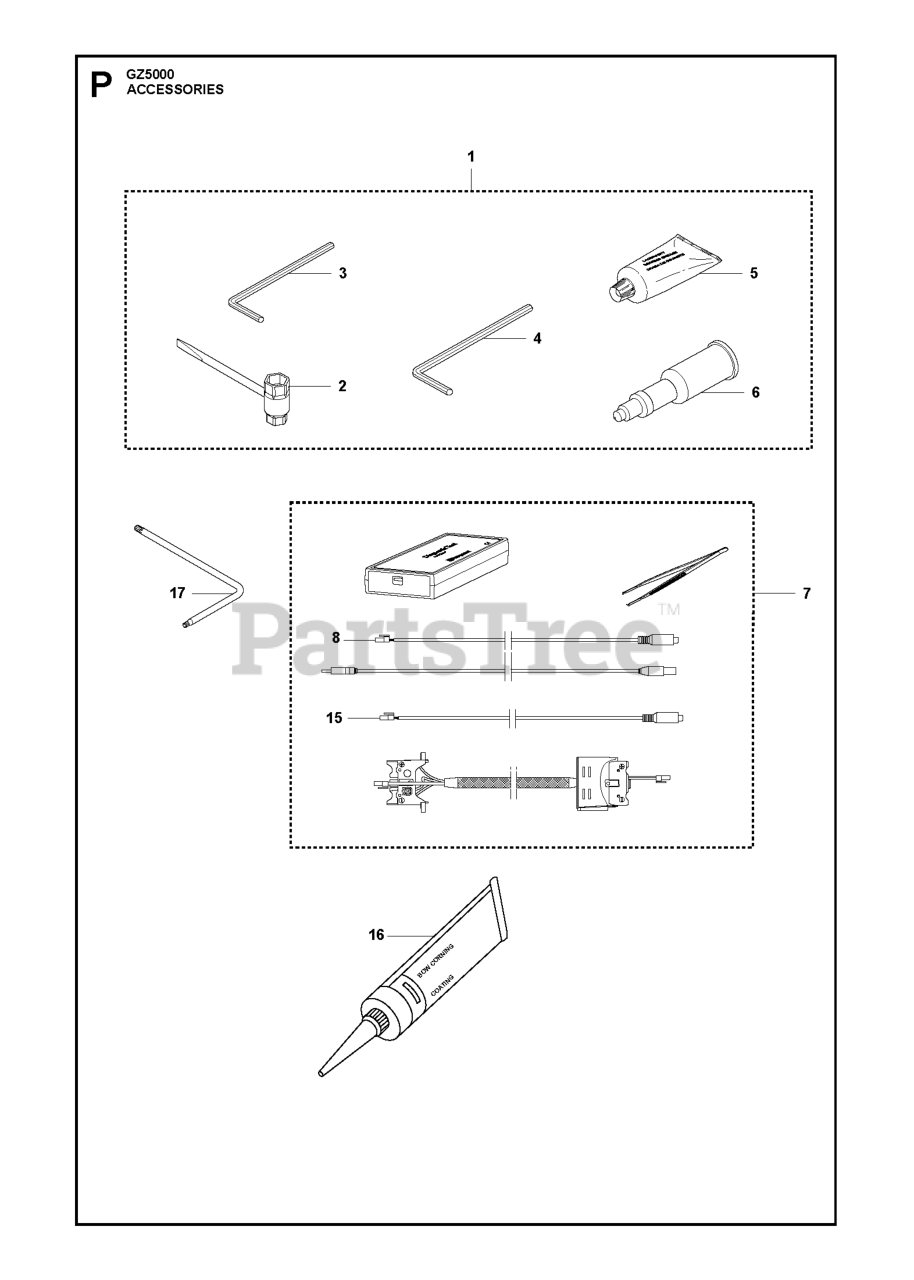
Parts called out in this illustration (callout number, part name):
2	COMBINATION WRENCH
3	L-SPANNER
4	L-SPANNER
6	GREASE GUN
7	DIAGNOSTIC TOOL KIT
8	CABLE ASSY
15	CABLE ASSY
16	SILICONE
